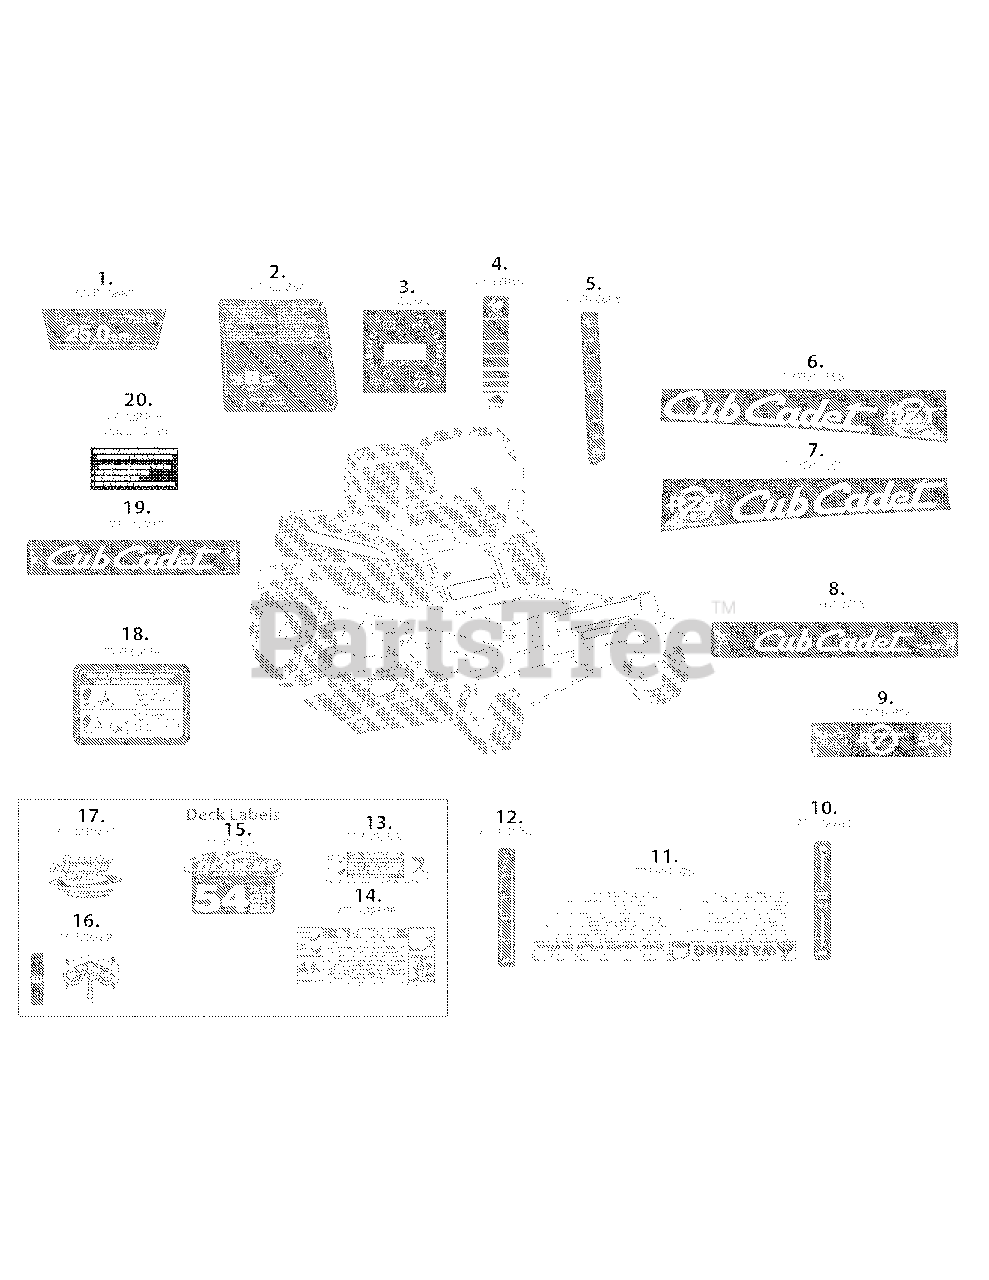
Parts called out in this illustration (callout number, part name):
1	LABEL-ENGINE FH721V KAW
2	LABEL-START INSTR RH POD
3	LABEL-HOUR METER LH POD
4	LABEL-THROTTLE LH POD
5	LABEL-FUEL LEVEL LH POD
6	LABEL-CUB CADET RZT RH POD
7	LABEL-CUB CADET RZT LH POD
8	LABEL-FRONT FRAME CUB CADET
9	LABEL-RZT 54 AXLE PIVOT
10	LABEL-PARK BRAKE
11	LABEL-COMMON WARNING
12	LABEL-HANDLE HEIGHT
13	LABEL-DANGER CHUTE
14	LABEL-RZT DECK WARNG STRAIGHT
15	LABEL-CYCLO CUT 54"
16	LABEL-BELT ROUTE
17	LABEL-RIDER:DECK WASH CUB
18	LABEL-TRNMSN RELEASE
19	LABEL-REAR FRAME CUB CADET
20	LABEL-EXPANSION TNK
